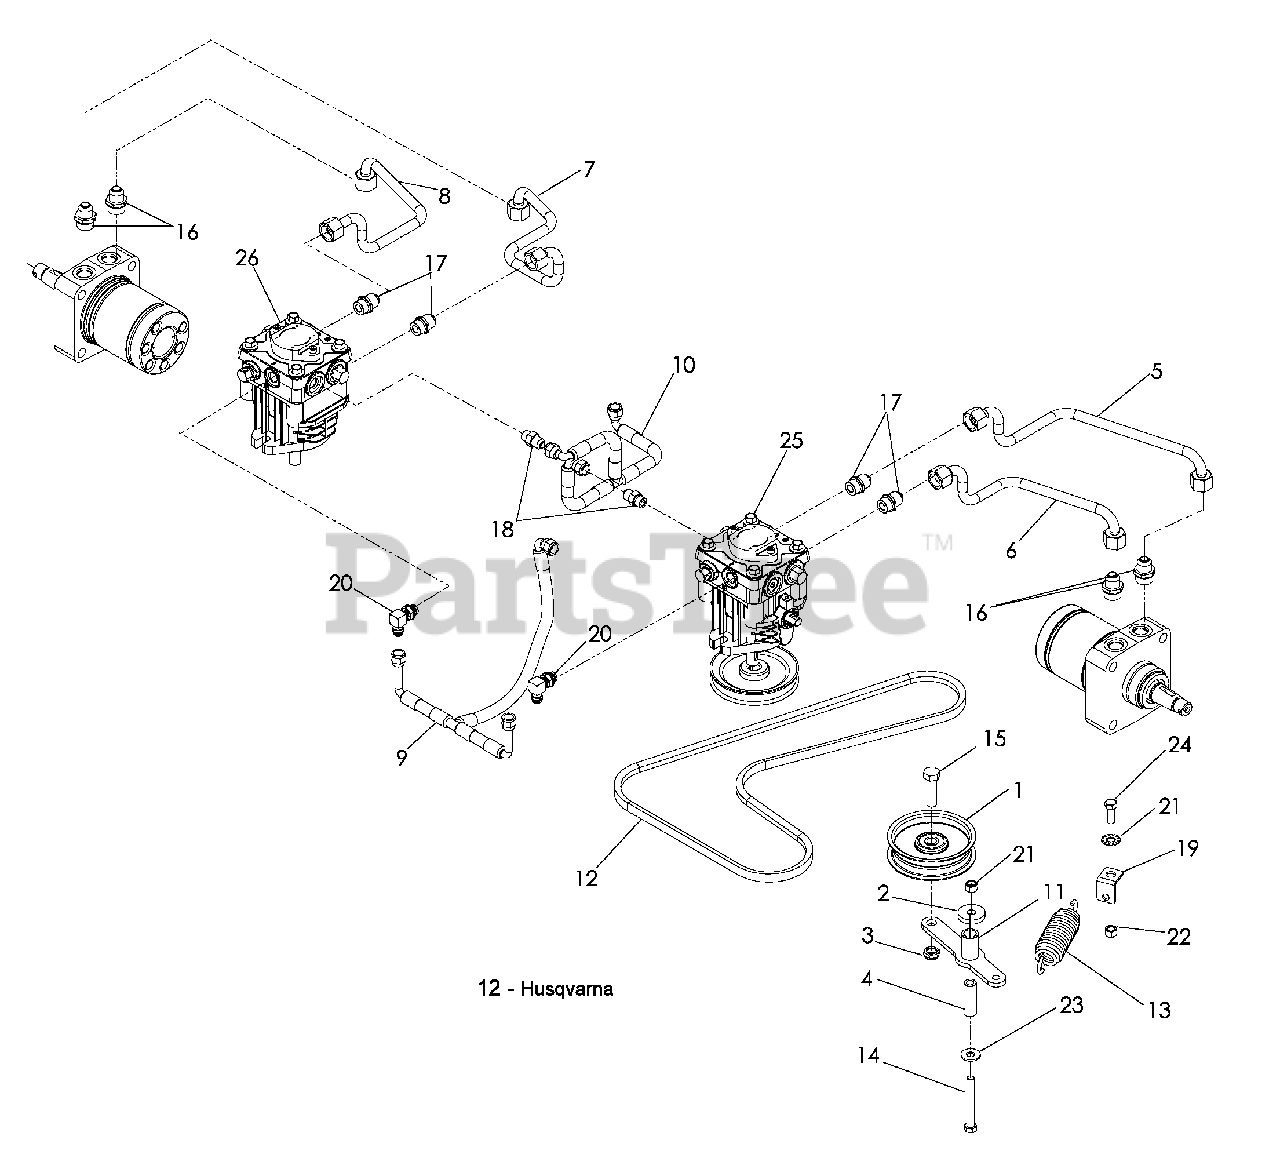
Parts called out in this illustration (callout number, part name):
1	IDLER PULLEY
2	WASHER 7/16
3	NUT ½-13 NYLOC
4	BUSHING 1.90
5	TUBE HYD LH-A
6	TUBE HYD LH-B
7	TUBE HYD RH-A
8	TUBE HYD RH-B
9	T-ASM HYD SUCTION
10	T-ASM HYD CASE DRAIN
11	BELT TENSIONER
14	HHB 3/8-16 x 3
15	HHB ½-13 x 1¾
16	FITTING HYDRAULIC
17	FITTING HYDRAULIC
18	FITTING HYDRAULIC
19	SPRING MOUNT
20	ADAPTER-MALE 9/16-18
21	WASHER 3/8 INT EXT L
22	NUT 3/8-16 NYLOC
23	WASHER 3/8
24	HHB 3/8-16 x 1
